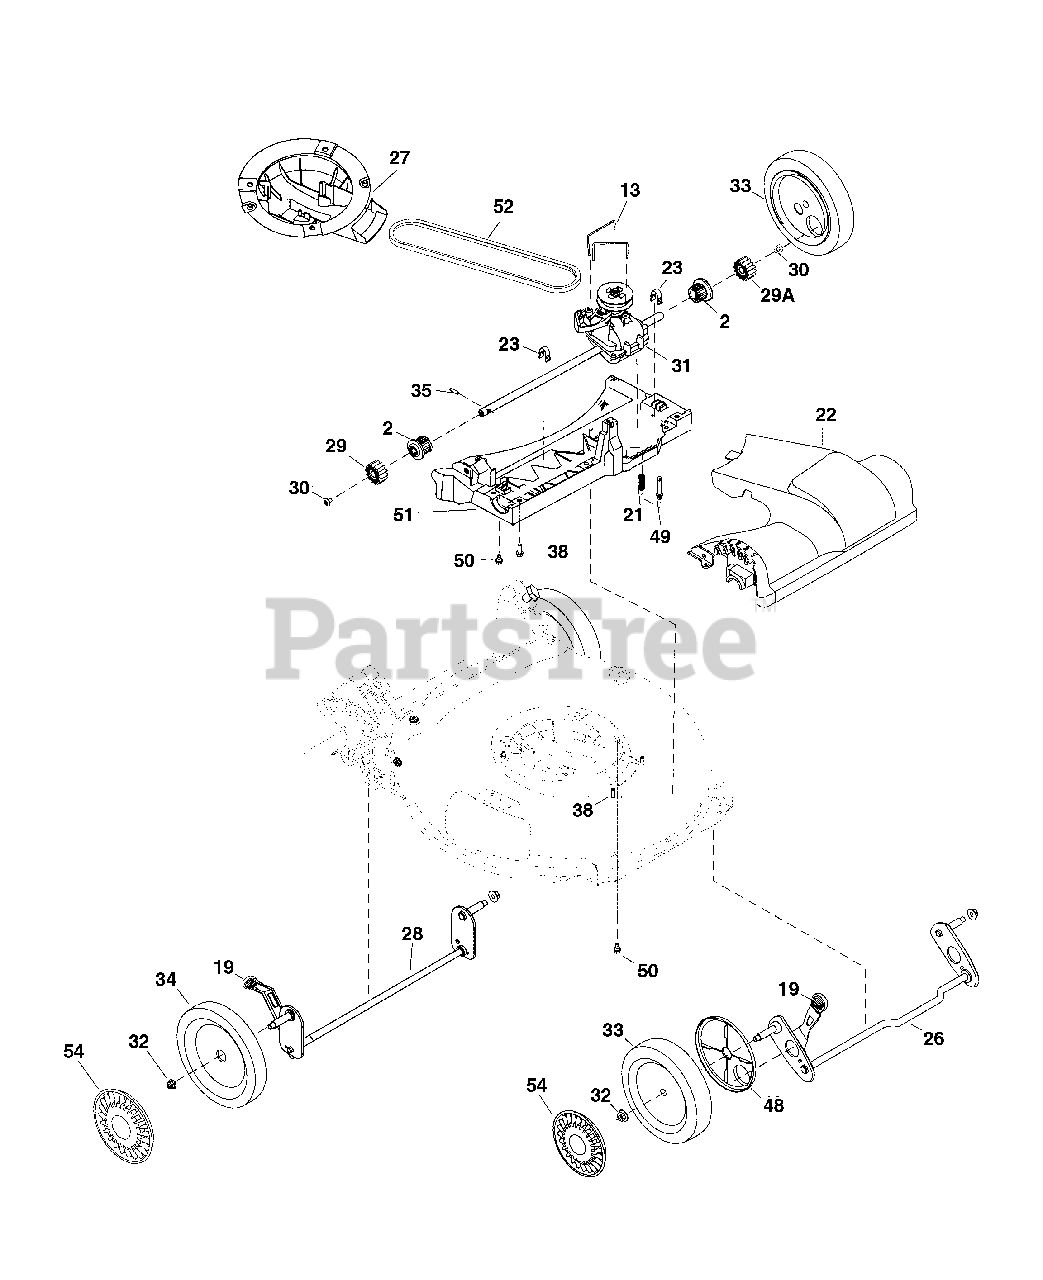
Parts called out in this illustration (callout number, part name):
2	ASSEMBLY, Bearing
13	WIRE, Transmission
19	KNOB, Adjustment Lever
21	SPRING, Compression
22	COVER, Front
23	CLIP, Front Axle
26	AXLE ASSEMBLY, Front
27	BAFFLE, Engine
28	AXLE ASSEMBLY, Rear
29	GEAR, 14T, RH
29A	GEAR, 14T, LH
30	SCREW, 1/4-20 x .390
31	TRANSMISSION
32	NUT, Hex Flange, Nylock, 3/8-16
33	WHEEL, Front
34	WHEEL, 8 x 2, Black
35	PIN, Dowel
38	SCREW, 1/4-15X3/4, Self-Tapping, BZ
48	COVER, Dust, Wheel
49	SPRING, Body
50	SCREW, Shoulder, 1/4-20 x 1/2
51	TRAY, Lower
52	V-BELT, 3L, 34.13, V-SPD
54	HUBCAP, Front, 8" Grey
